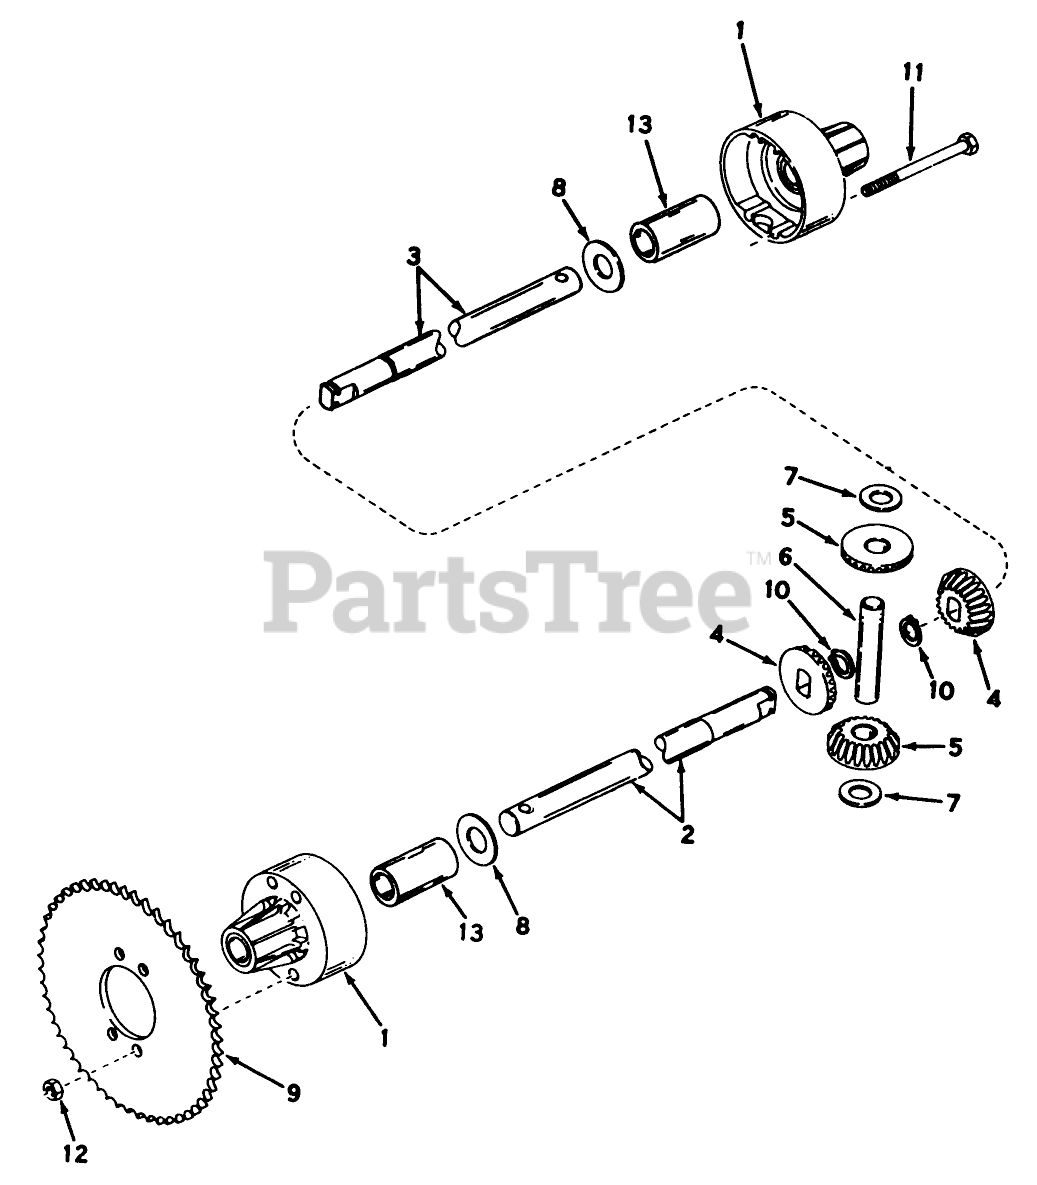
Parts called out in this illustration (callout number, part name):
1	Housing, Differential Carrier (Incl. No. 13)
2	Axle, Short
3	Axle, Long
4	Gear, Bevel
5	Gear, Pinion
6	Pin, Drive
7	Washer, Thrust
9	Sprocket
10	Ring, Snap
11	Screw, Hex Hd., 5/16-18 x 4
12	Nut, Lock, 5/16-18
